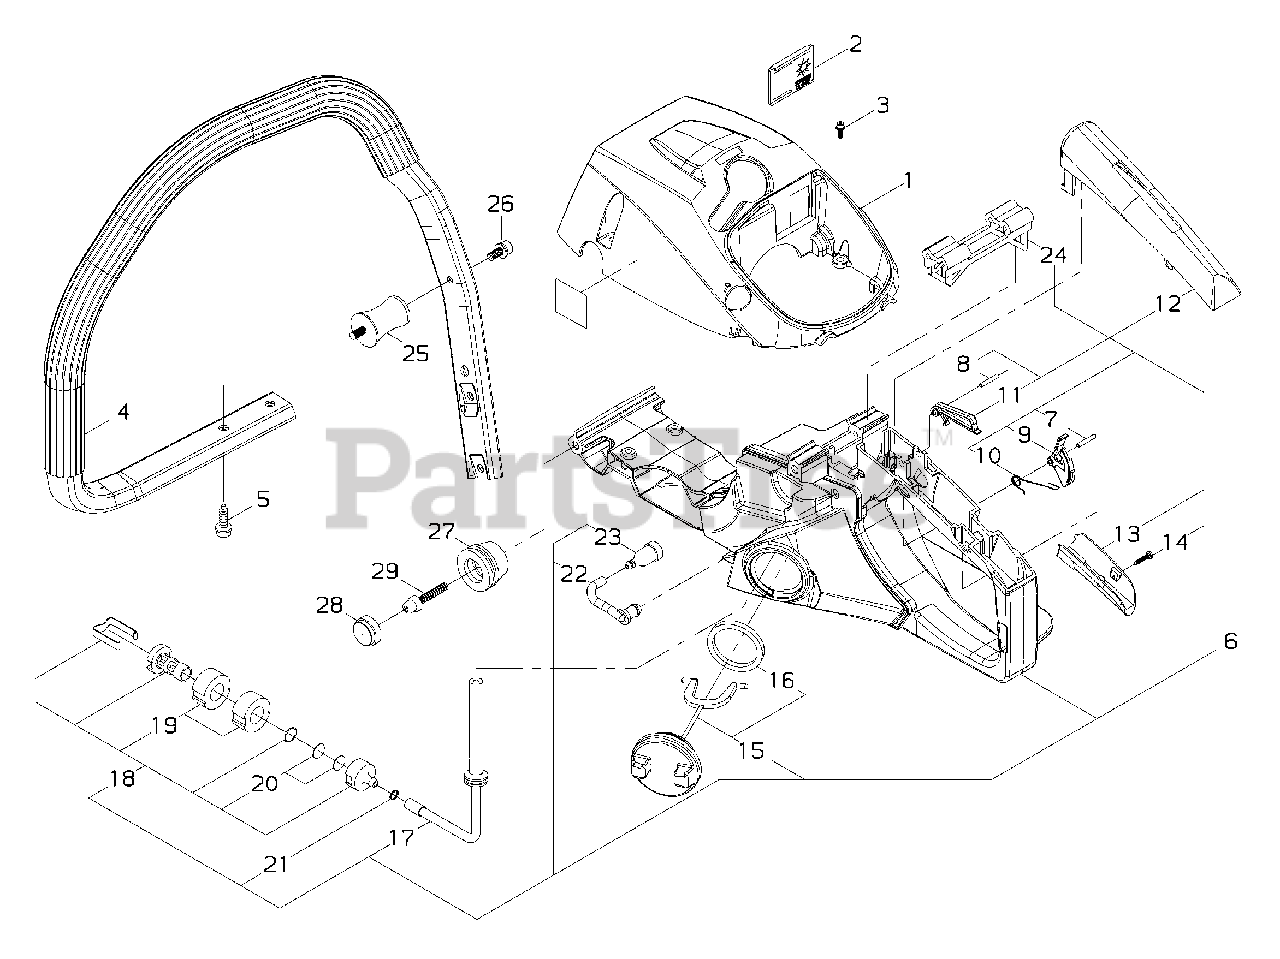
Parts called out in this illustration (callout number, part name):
1	COVER, ENGINE
2	SHUTTER
3	SCREW - 4X16
4	HANDLE - FRONT
5	BOLT - 5X16 -- TAPPING
6	HANDLE ASSY - REAR
7	PIN - 4X25
8	PIN
9	TRIGGER, THROTTLE
10	SPRING, LEVER
11	LEVER, TRIGGER LOCKOUT
12	GRIP - UPPER
13	GRIP - LOWER
14	SCREW - 4X20 -- TAPPING
15	CAP ASSY
16	GASKET, CAP
17	PIPE - FUEL
18	FILTER, FUEL
19	FILTER, FUEL
20	SCREEN, FILTER
21	RING, RETAINING - 6
22	PIPE
23	ELEMENT, BREATHER
24	CUSHION
25	CUSHION
26	SCREW - 4X10
27	CUSHION
28	PLUG
29	BOLT
